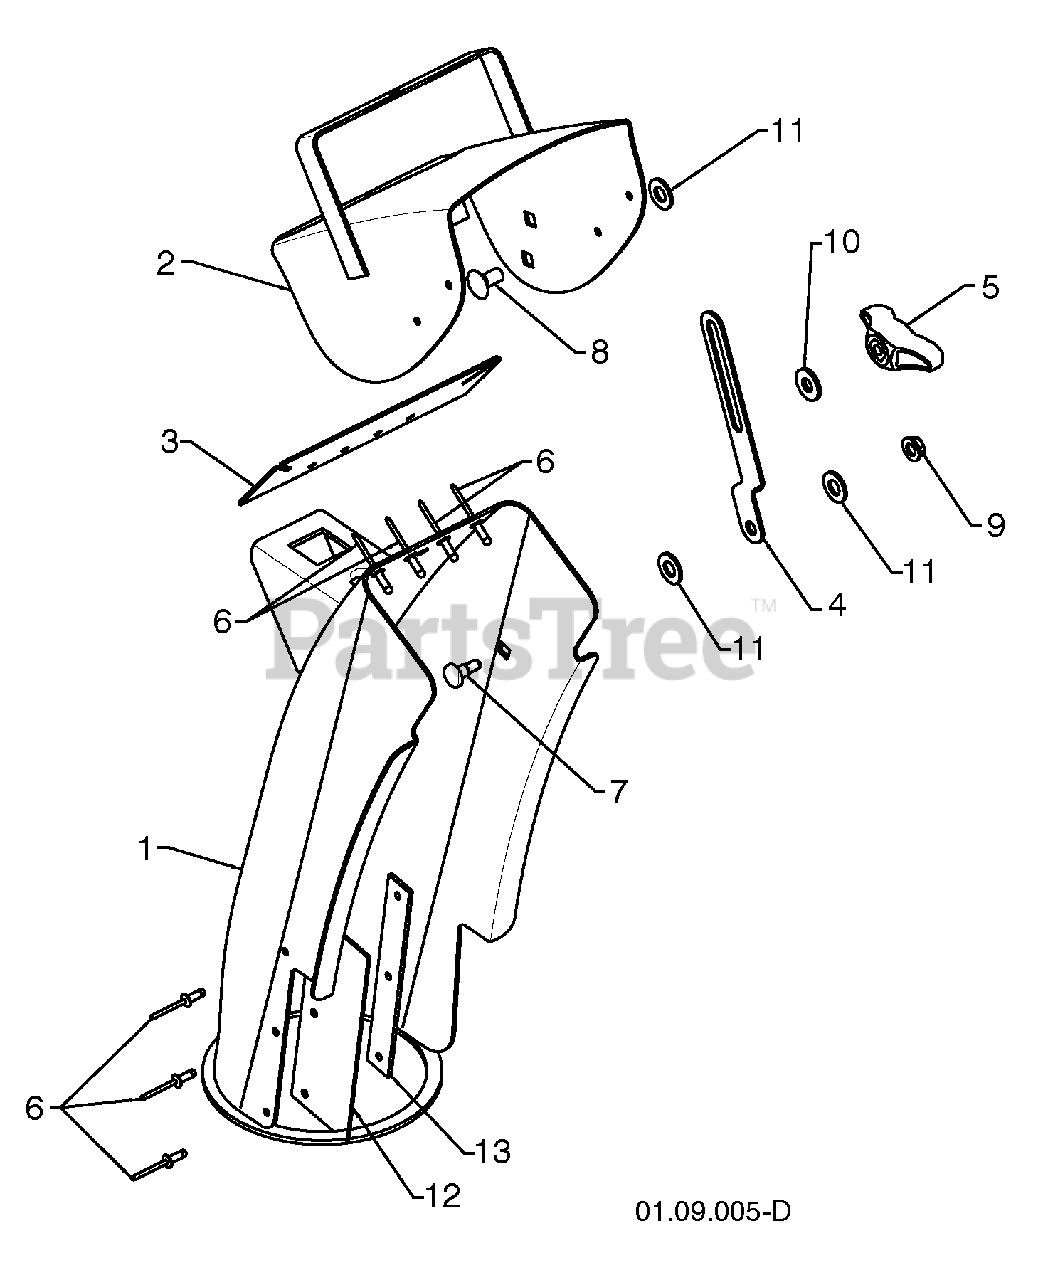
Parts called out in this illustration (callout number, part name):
1	CHUTE WELDMENT
2	DEFLECTOR WELDMENT
3	DEFLECTOR SEAL
4	STRAP
5	KNOB BLACK
6	POP RIVET
7	SHOULDER BOLT 1/4-20 X .704
8	CARRIAGE BOLT 5/16-18 X .625
9	NUT 1/4-20
10	WASHER
11	PLASTIC WASHER
12	CHUTE SNOW SHIELD
13	SHIELD RETAINER STRAP
